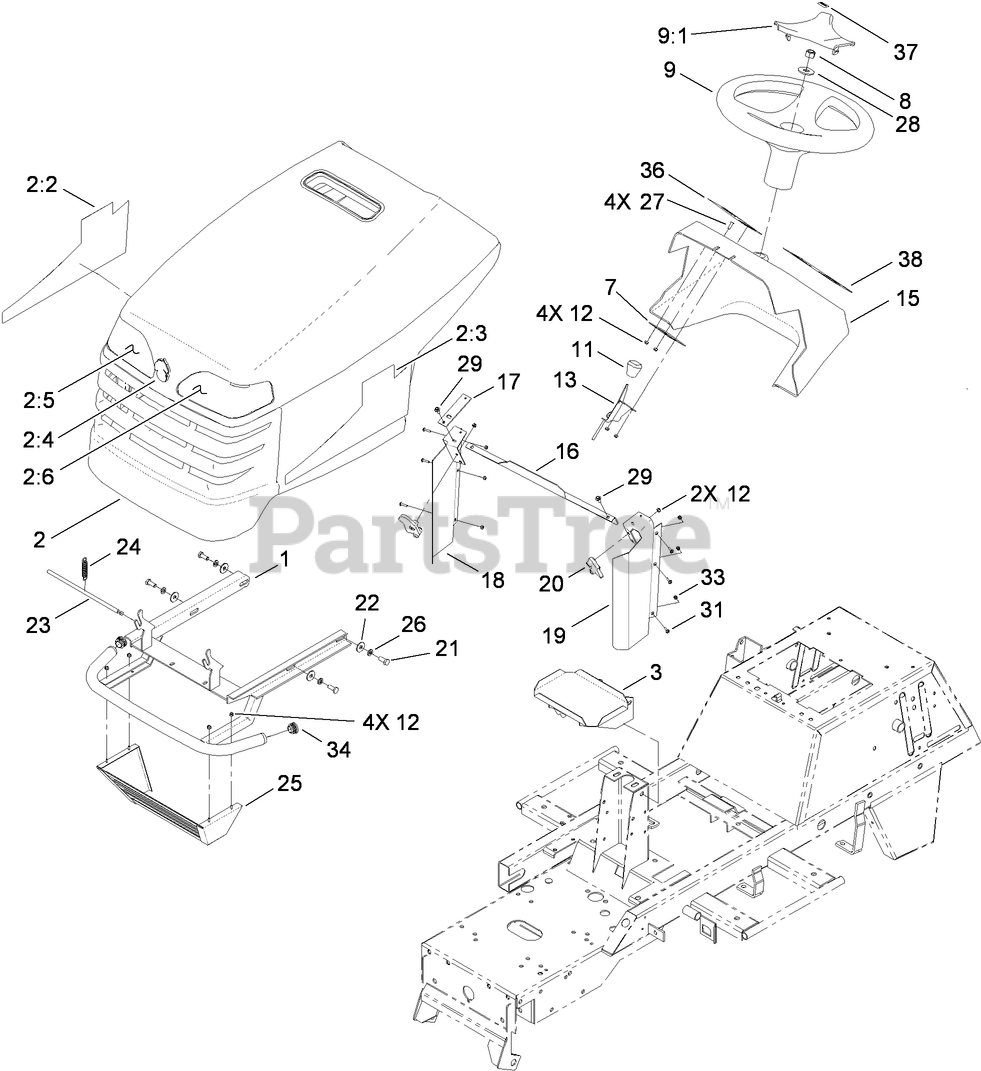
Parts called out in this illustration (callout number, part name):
1	SUPPORT-BUMPER
2	HOOD ASM
2:2	DECAL-HOOD, RH
2:3	DECAL-HOOD, LH
2:4	EMBLEM
2:5	LENS-HEADLAMP, RH
2:6	LENS-HEADLAMP, LH
3	TRAY-BATTERY
8	NUT-HEX
9	WHEEL-STEERING
9:1	COVER-WHEEL, STEERING
12	NUT-LOCK
13	CABLE-THROTTLE AND CHOKE
15	PANEL-DASH
17	BRACKET
18	PANEL-RIGHT
19	PANEL-LEFT
20	LATCH-HOOD
21	SCREW-HH
22	WASHER-PLAIN
23	BAR-SAFETY
24	SPRING-HOOD
25	GUARD-MUFFLER
26	WASHER-LOCK
28	Washer
33	NUT-HEX
34	PLUG-END, TUBE
36	DECAL-CHOKE/THROTTLE/KEY
37	DECAL
38	DECAL-PTO
